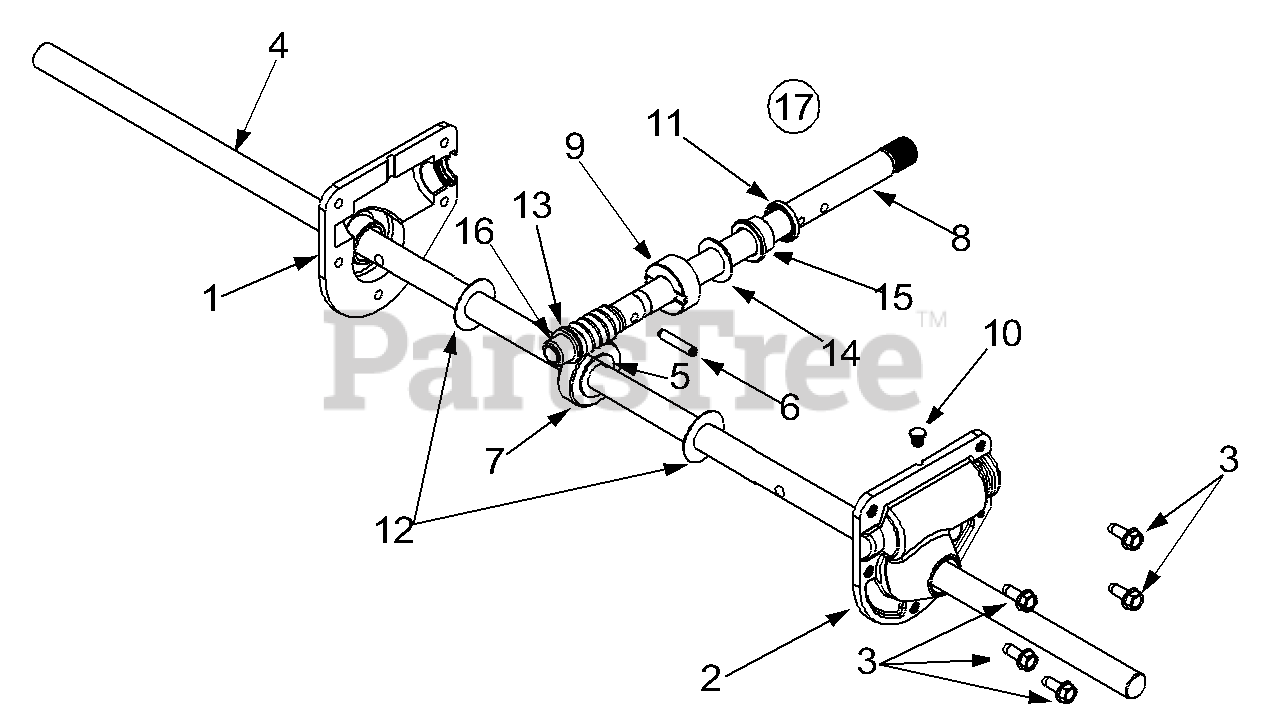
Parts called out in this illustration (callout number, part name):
1	Housing-R.H.
2	Hex Screw 1/4-20 x .75
3	Spiral Axle 24"
4	Key
5	Pin-Spiral
6	Shaft-Worm
7	Gear-Worm
8	Collar-Thrust
10	Seal-Oil
11	Washer-Flat
12	Washer-Flat
13	Washer-Flat
14	Grease
15	Bearing-Flange
16	Bearing-Flange
17	Ass'y. Complete 24"
